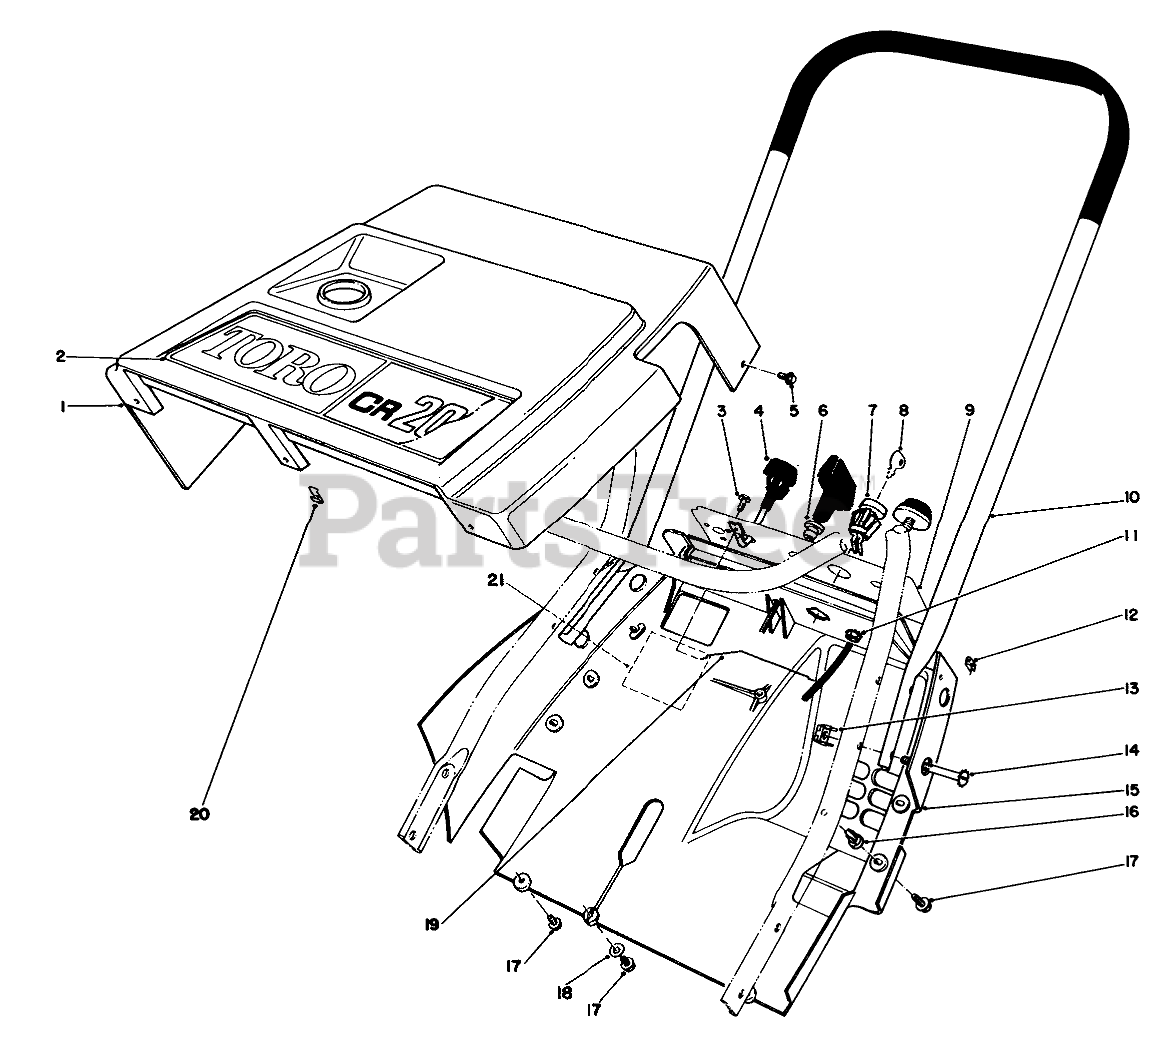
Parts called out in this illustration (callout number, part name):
1	Shroud-Upper
2	Decal-Toro (Model 38110C)
3	SCREW-PLASTITE
4	CHOKE CONTROL ASM
5	SCREW-HWHTF
6	GUIDE-ROPE, STARTER
7	SWITCH
8	KEY-IGNITION
9	Decal-Control Panel (Model 38110C)
10	Handle-Upper
11	NUT-KEPS
13	TINNERMAN NUT
14	SCREW-HEX HD SLOT
15	LOWER SHROUD
16	Nut-Push
17	SCREW-HWHTF
18	WASHER-FLAT
19	CONTROL WIRE
20	NUT "U"
21	DECAL - CSA
